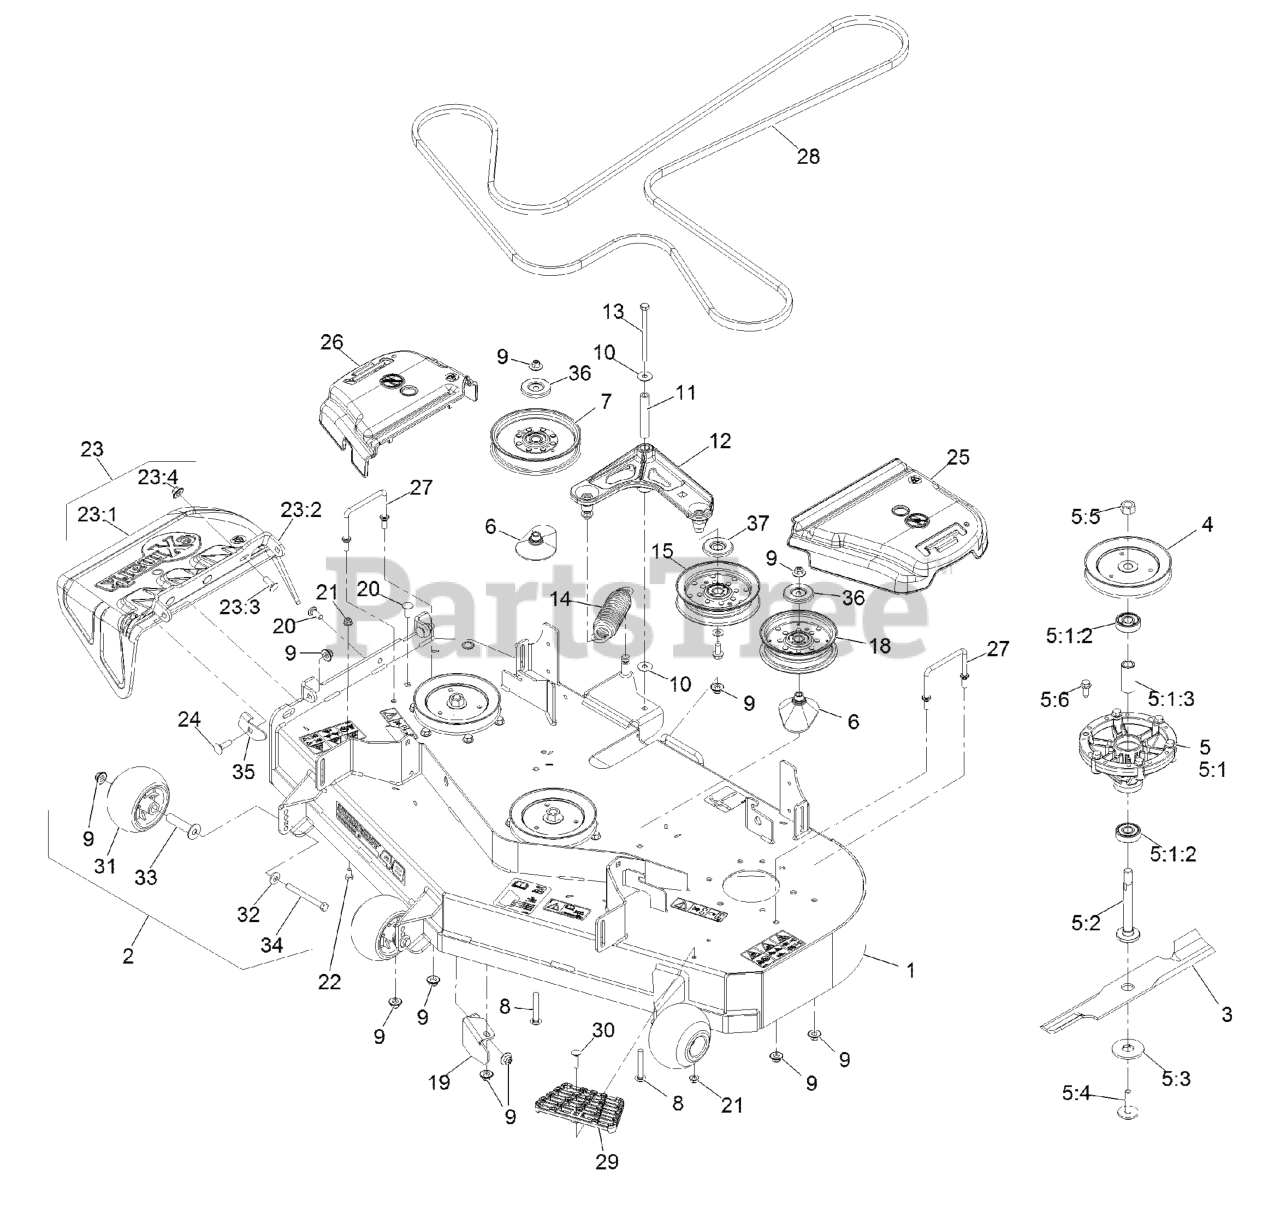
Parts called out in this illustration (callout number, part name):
1	ASM-DECK W/DECALS 483
2	KIT, ANTI-SCALP ROLLER
4	SHEAVE,BLADE DRIVE 5.90
5	ASM, CUTTER HOUSING COMPL
5:1	ASM-CUTTER HOUSING
5:1:2	BEARING
5:1:3	SPACER-BEARING
5:2	SPINDLE-HEX PILOT
5:3	WASHER-HEX BLADE DRIVE
5:4	BOLT-BLADE, SEM
5:5	NUT-HEX
5:6	SCREW-FORMING, THREAD
6	SPACER-PULLEY
7	IDLER-PULLEY, FLAT 6.00X1
8	SCREW-CARR
9	Nut-Nyloc 3/8-16 Flg
11	BUSHING
12	IDLER ARM ASM
13	SCREW-HH
14	SPRING-EXTENSION
15	IDLER-PULLEY, FLAT
18	IDLER-PULLEY, FLAT 5.00X1
19	BAFFLE,DISCHARGE 483
20	SCREW-CARR
21	NUT-HF, NI
22	SCREW-HH
23	ASM,DISCHARGE CHUTE
23:1	CHUTE,DISCHARGE
23:2	BRACKET,DISCHARGE CHUTE
23:3	SCREW-CARR
23:4	Nut-Nyloc 3/8-16 Flg
24	BOLT-CARR
25	COVER-BELT, LH
26	COVER-BELT, RH
27	WIREFORM-COVER
28	BELT-V
29	STEP-DECK
30	Bolt-Carriage 5/16-18 X 1 1/4
31	ROLLER-SCALP, ANTI
32	WASHER-BELLEVILLE
33	AXLE, ROLLER
34	SCREW-HH 3/8-16 X 3 3/4 GR 8
35	STOP-DISCHARGE CHUTE
36	SHIELD-DUST
37	SHIELD-GUARD, DUST
